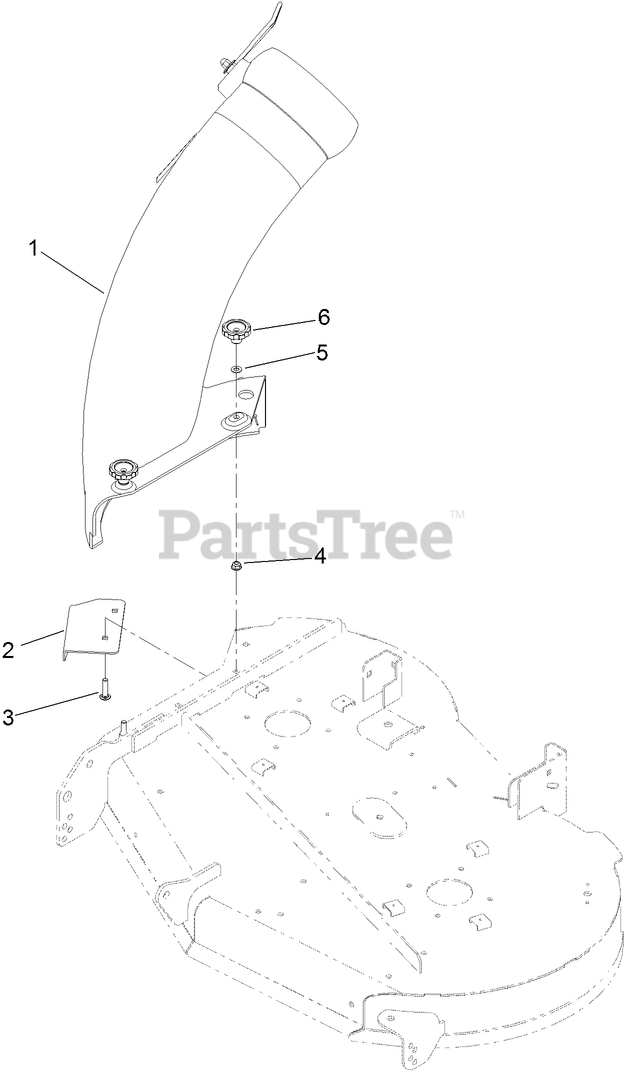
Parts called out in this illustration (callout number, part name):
1	CHUTE ASM
2	BAFFLE-CUTOFF
3	SCREW-CARR
4	NUT-HF, NI
5	WASHER-PLAIN
